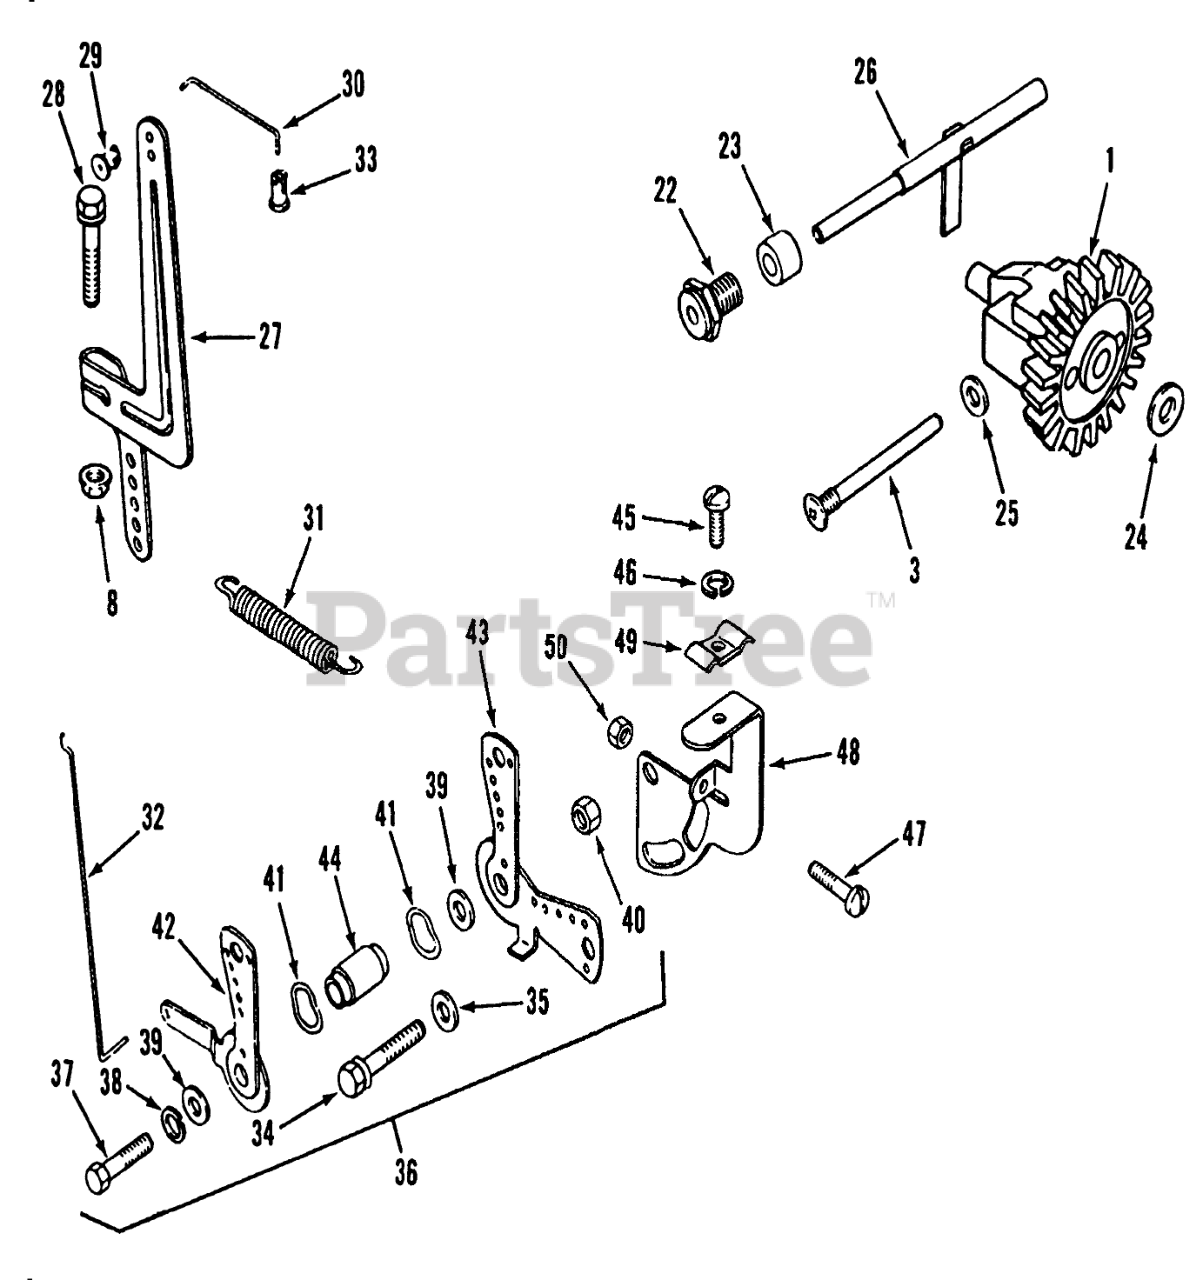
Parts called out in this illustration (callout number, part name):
1	Kit-Governor Gear(Includes 24)
3	Govenor Stop Pin
8	Palnut
22	Bushing
23	Spacer
24	Washer
25	Washer
26	Governor Cross Shaft Kit
27	Governor Lever
28	Screw
29	Bushing
30	Linkage (Governor to Carb.)
31	Spring (Governor to Cab.)
32	Choke Linkage (Carb. to Choke Shaft)
33	Bushing
34	Screw
35	Washer
36	Choke Lever Assembly (Includes Items 37 thru 44)
37	Screw
38	Washer-Lock
39	Screw
41	Washer
42	Choke Control Lever
43	Lever-Throttle Control
44	Space
45	F.H.M. Screw #10-24 x 1/2
46	Lockwasher #10
47	Screw
48	Bracket-Clutch Control
49	Clamp
